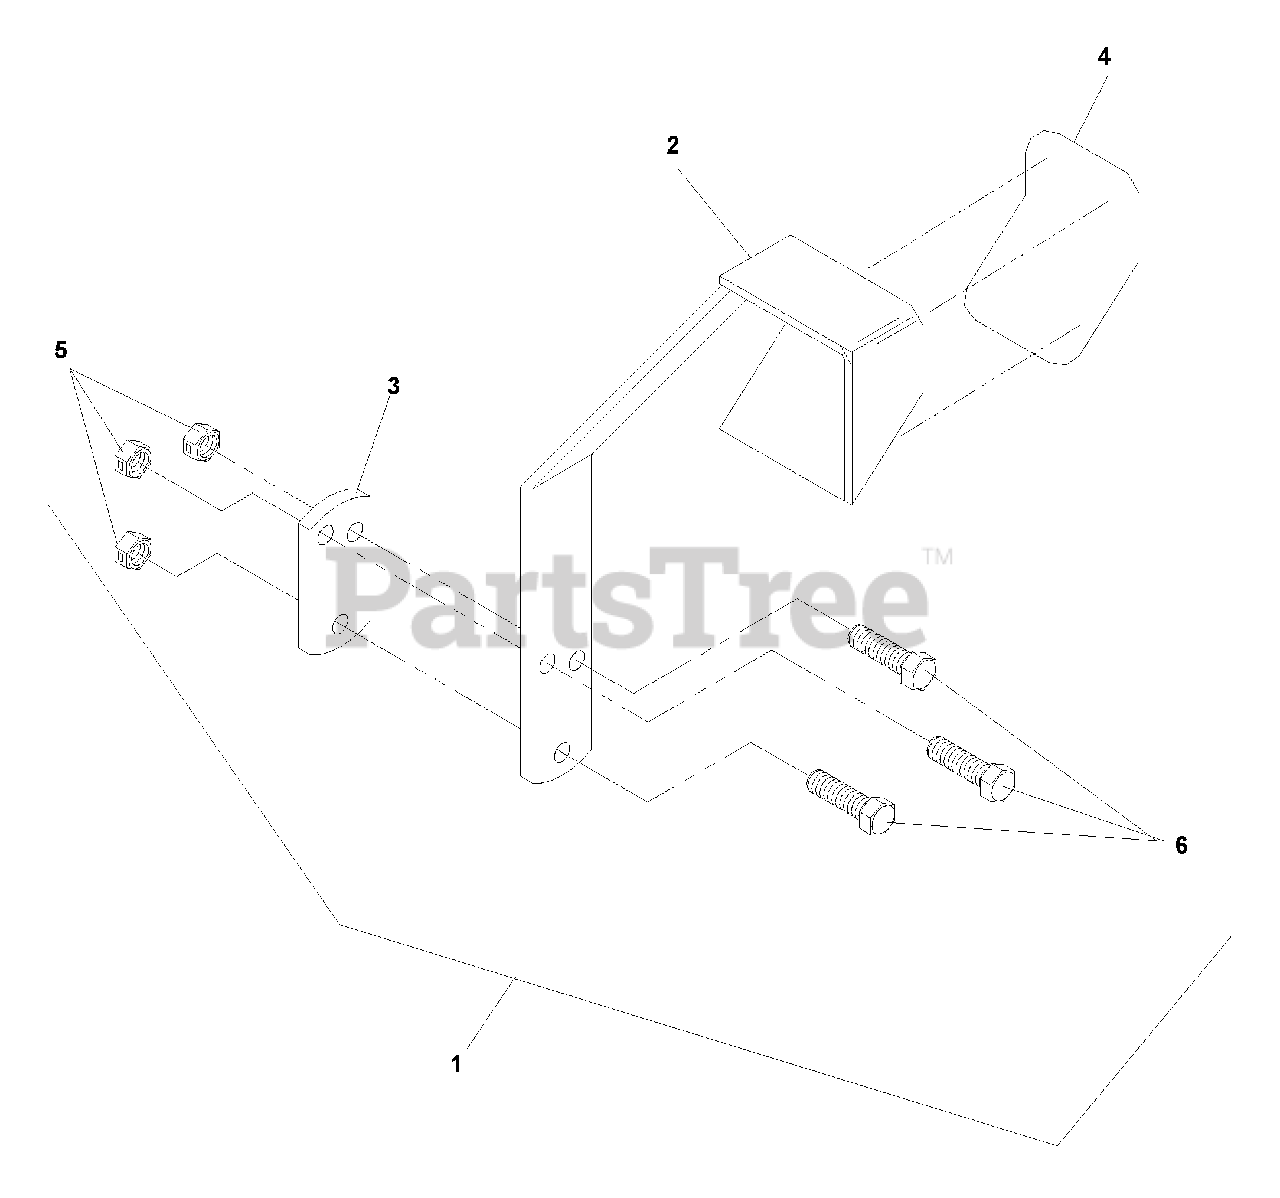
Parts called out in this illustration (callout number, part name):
1	LIFT PEDAL KIT
2	LIFT PEDAL
3	TIGHTENING PLATE
4	PAD-ANTI SKID
5	NUT, 3/8-16, NYLOC
6	HCS, 3/8-16 X 1 1/2, GR5
